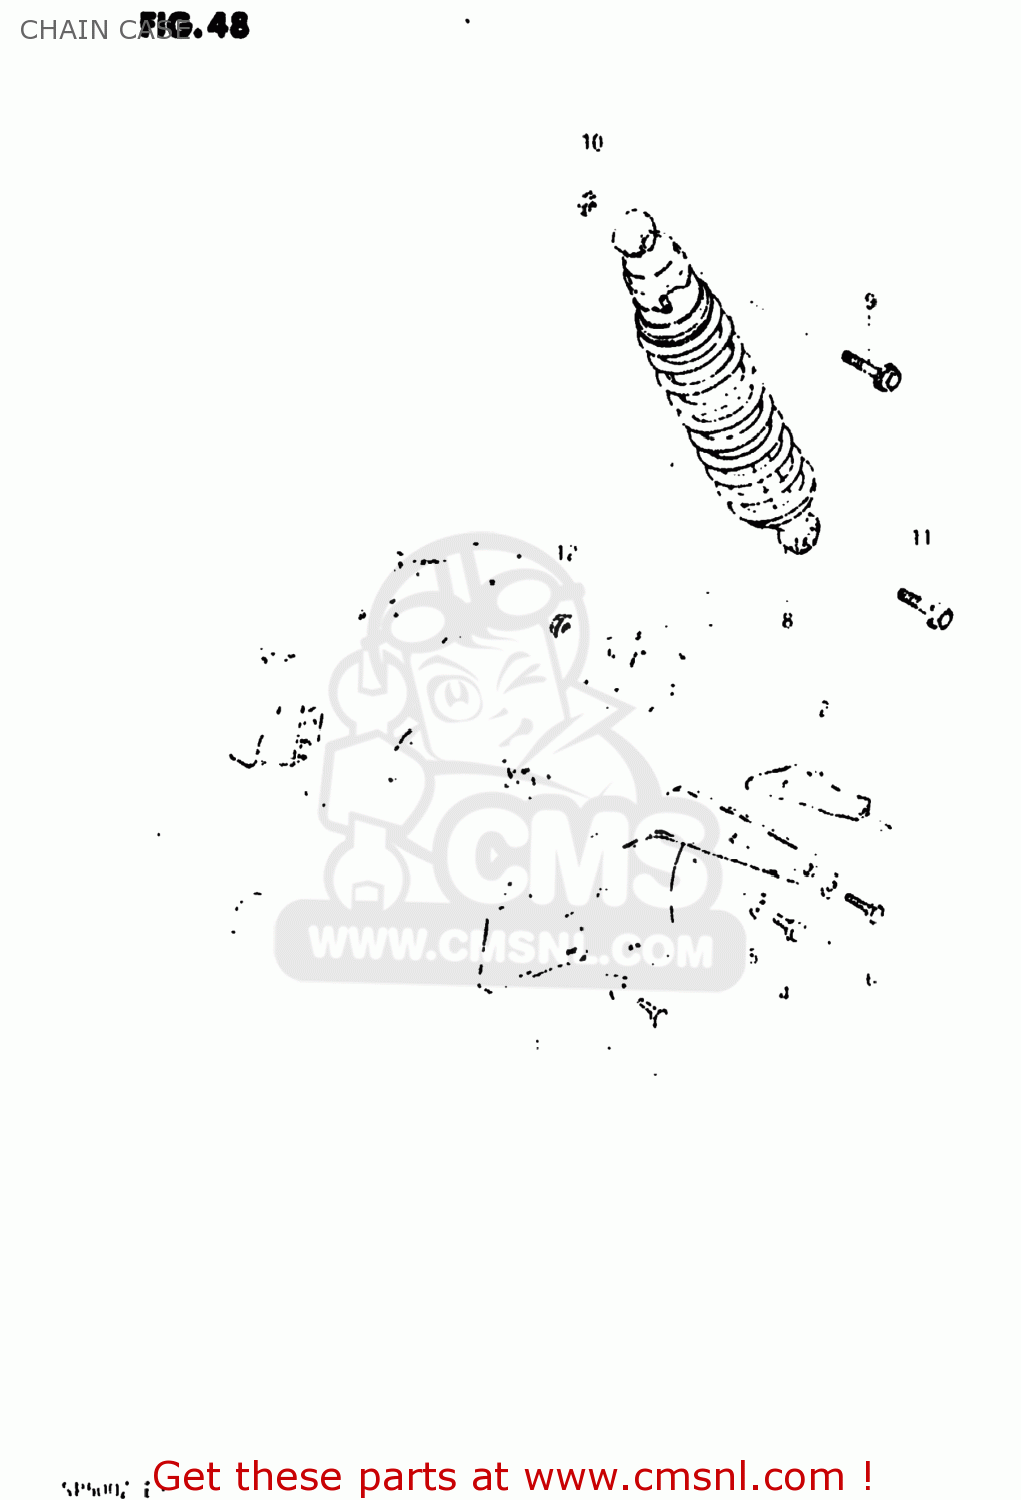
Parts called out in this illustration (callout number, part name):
1	CASE,CHAIN
2	REINFORCEMENT,CHAIN CASE
3	BOLT
4	BOLT 6X8
5	WASHER
6	BOLT
7	WASHER
8	ABSORBER ASSEMBLY,REAR SHOCK
9	BOLT(10X40)
10	NUT
11	BOLT(10X50)
12	NUT
